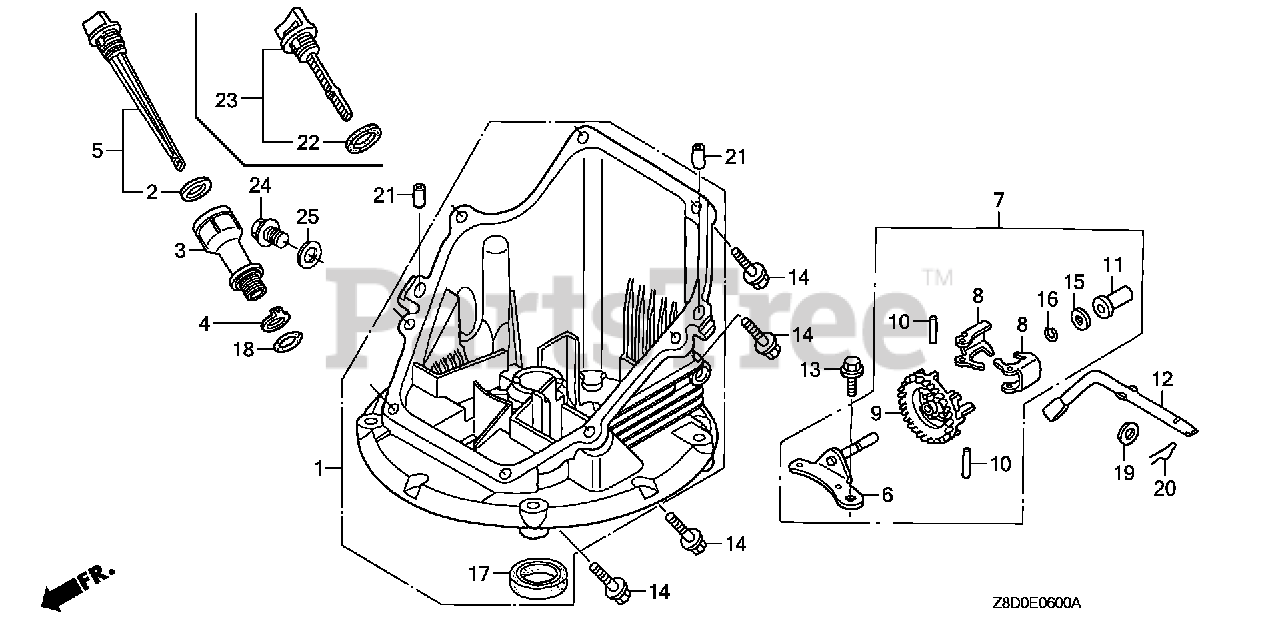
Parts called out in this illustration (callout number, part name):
1	PAN ASSY., OIL
2	GASKET, OIL FILLER CAP Use up to Engine SN 1257294.
3	EXTENSION, OIL FILLER
4	WASHER, EXTENSION LOCK
5	DIPSTICK, OIL
6	SHAFT, GOVERNOR HOLDER
7	GOVERNOR ASSY.
8	WEIGHT, GOVERNOR
9	HOLDER, GOVERNOR WEIGHT
10	PIN, GOVERNOR WEIGHT
11	SLIDER, GOVERNOR
12	SHAFT, GOVERNOR ARM
13	BOLT, FLANGE (6X14)
14	BOLT, FLANGE (6X25) Use up to Engine SN 2056819.
15	WASHER, THRUST (6MM)
16	CLIP, GOVERNOR HOLDER
17	OIL SEAL (28X41.25X6)
18	O-RING (14.8X2.4) (ARAI)
19	WASHER, PLAIN (6MM)
20	PIN, LOCK (8MM)
21	PIN, DOWEL (8X20)
